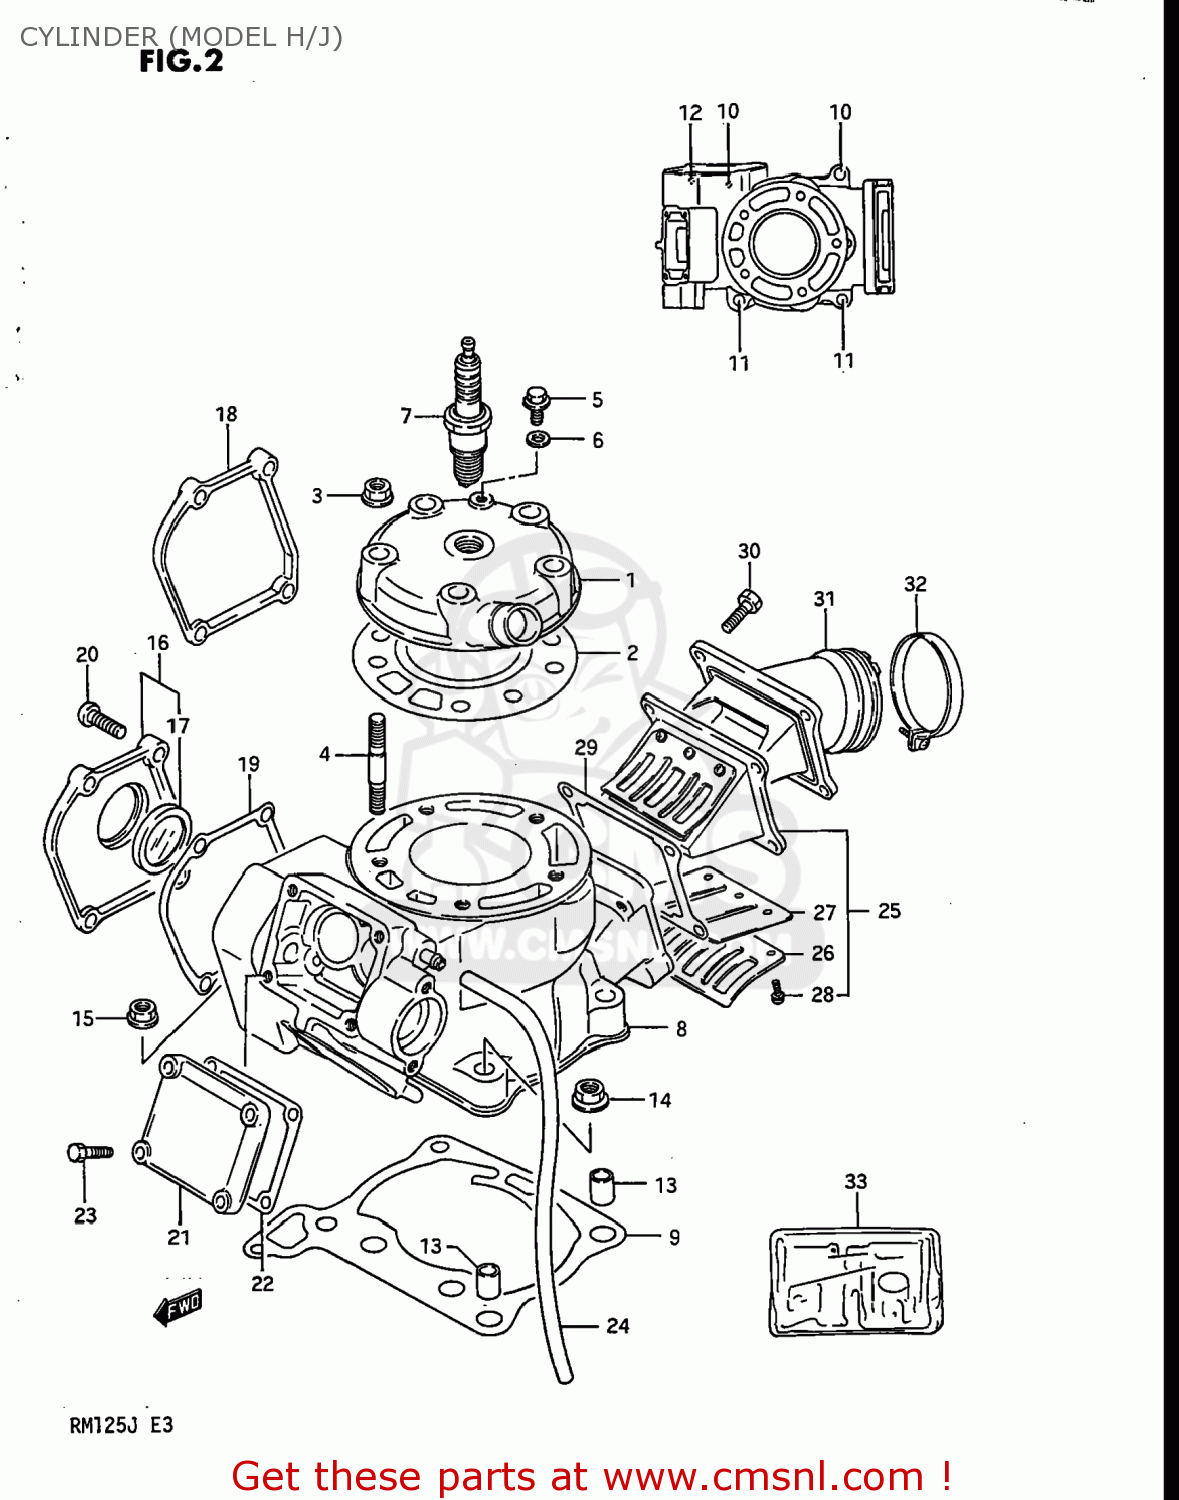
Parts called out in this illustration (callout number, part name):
1	HEAD,CYLINDER
2	GASKET,CYLINDER HEAD (NAS)
3	NUT
4	BOLT,STUD
5	UNION
6	GASKET(6.2X11X1).2 (NAS)
7	SPARK PLUG
8	CYLINDER
9	GASKET,CYLINDER (MCA)
10	STUD
11	BOLT,STUD
12	STUD
13	PIN
14	NUT
15	NUT
16	COVER COMP,CYLINDER
17	LENS,CYLINDER COVER
18	COVER,CYLINDER NO.1
19	GASKET,CYLINDER COVER (MCA)
20	SCREW
21	COVER,CYLINDER
22	GASKET,CYLINDER COVER (MCA)
23	BOLT
24	HOSE
25	VALVE ASSEMBLY,REED
26	STOPPER,REED VALVE
27	VALVE,REED
28	SCREW,REED VALVE
29	GASKET,REED VALVE (MCA)
30	BOLT
31	PIPE,INTAKE
32	CLAMP
33	GASKET SET (MCA)
